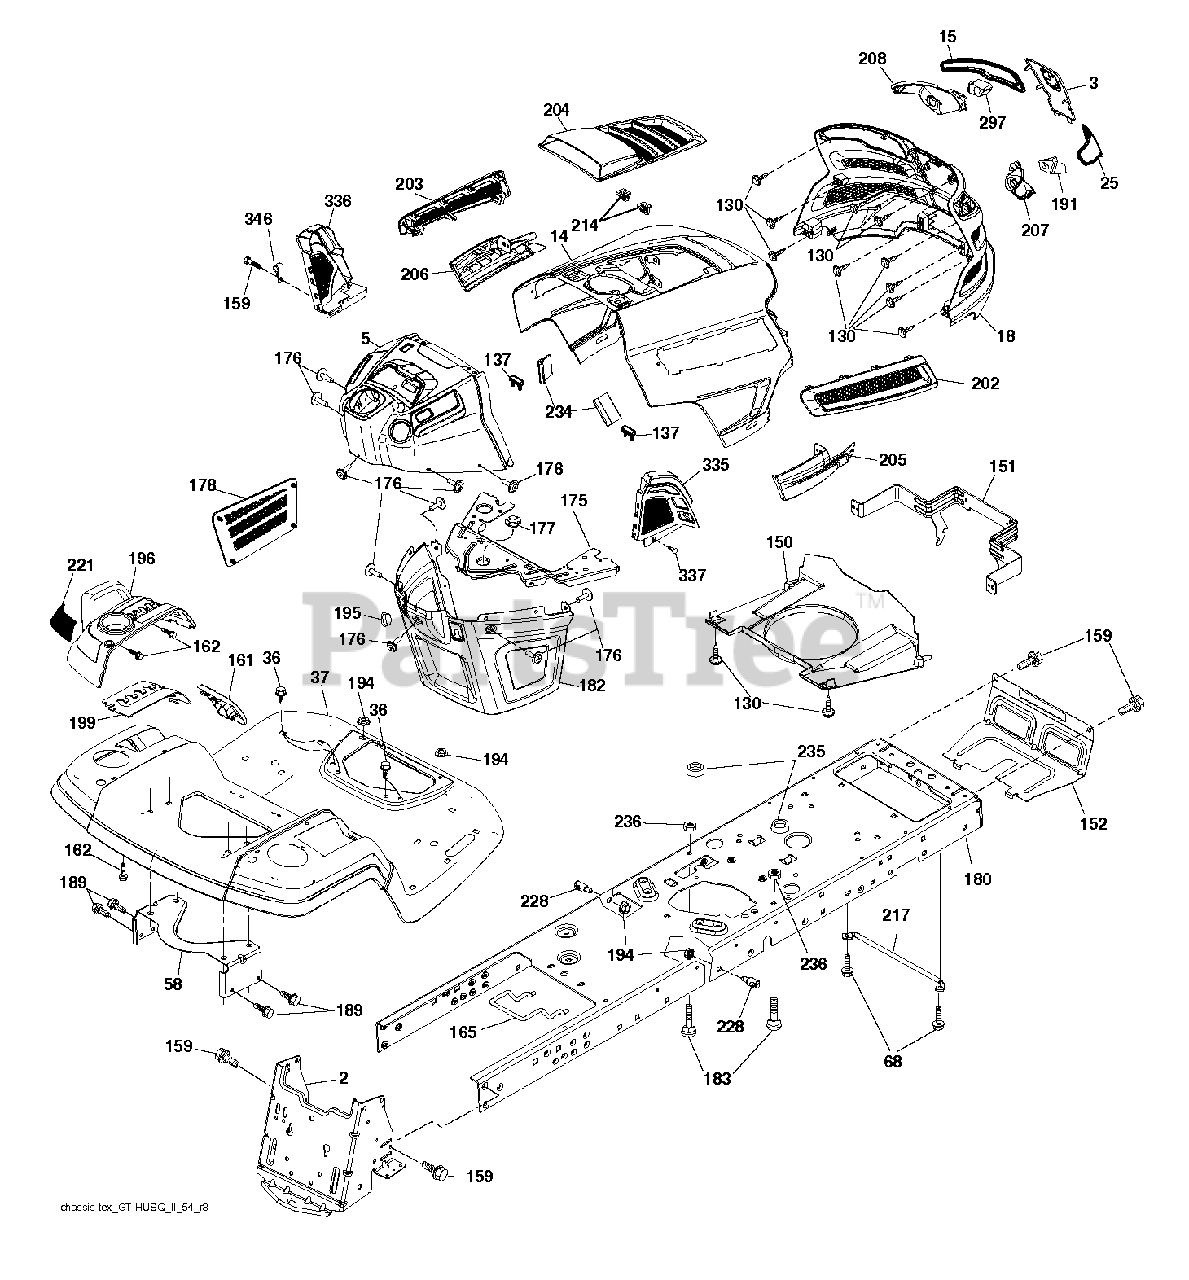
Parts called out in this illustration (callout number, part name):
2	DRAWBAR.STGT
3	APPLIQUE.SUBASM.GT.HUSQ.II
5	DASH.UPR.ASSY.GT2.SRVMNDER.PTO
14	HOOD.ASM.HUSQVARNA.GT.TEX.ORAN
15	LENS.HEADLIGHT.LH.GTII.2011
18	GRILLE.SUBASM.GT.HUSQ.II
25	LENS.HEADLIGHT.RH.GTII.2011
36	SCREW 5/16"
37	FENDER.PNT.TX.GT.CH/FW/DL.HUSQ
58	BRKT.SUPPORT.FNDR/TANK
68	SCREW LT
130	SCREW.#10 X 0.750.BOS
137	BUMPER DASH
150	AIR.DUCT.GTV.BLACK
151	BRACKET.PIVOT.HOOD.GT.HUSQ.II
152	SHIELD.BROWNING/DEBRIS
159	SCREW, 3/8-16X3/4
161	CONSOLE.WINDOW.FUEL.HUSQ.GT
162	SCREW.HI-LO.CONSOLE
165	SUPPORT.TANK.REAR.B/TE
175	PLATE.CROSSMEMBER.HUSQ
176	SCREW.#10-24X5/8.RN.QU
177	BUSHING, STEERING
178	CARGO.ASM.NET.TXGT.W/C
180	CHASSIS.STAMPING.LT/GT
182	DASH.LOWER.COMMON.12V.ADAPTOR
183	BOLT.5/16-18X1-1/4 FULL THD
189	SCREW
191	INSERT.REFLECTIVE.RH.HUSQ.GTII
194	NUT LOCK HEX FLANGE 5/16-18
195	PLUG.HOLE.DASH.LOWER.12V.BLK
196	CONSOLE.ASM.DECKLIFT.HUSQGT.DL
199	PLATE.DECK.LIFT.HUSQVARNA.GT
202	VENT.SIDE.RH.GT.HUSQ.II.
203	VENT.SIDE.LH.GT.HUSQ.II.498
204	VENT.TOP.HUSQ.GT2
205	SIDE.TRIM.RH.GT.HUSQ.II
206	SIDE.TRIM.LH.GT.HUSQ.II.GRAY
207	BEZEL LIGHT.RH.GT.II.MYLAR
208	BEZEL LIGHT.LH.GT.II.MYLAR
214	CLIP.RETAINER.TINNER.
217	ROD.PIVOT.HOOD
221	REFLECTOR.LH.TEX GT HU
228	STUD.FASTNER.W/ANTI-ROTATE
234	BUMPER.HOOD.TEX.HUSQVARNA
235	SPACER FENDER
236	NUT.CENTERLOCK.5/16-
297	INSERT.REFLECTIVE.LH.HUSQ.GTII
335	COVER.RH.CLOSE.OUT.BLACK
336	COVER.LH.CLOSE.OUT
337	CLIP.XMAS.TREE.ITW.2622-00
346	CLIP,INSULATOR
